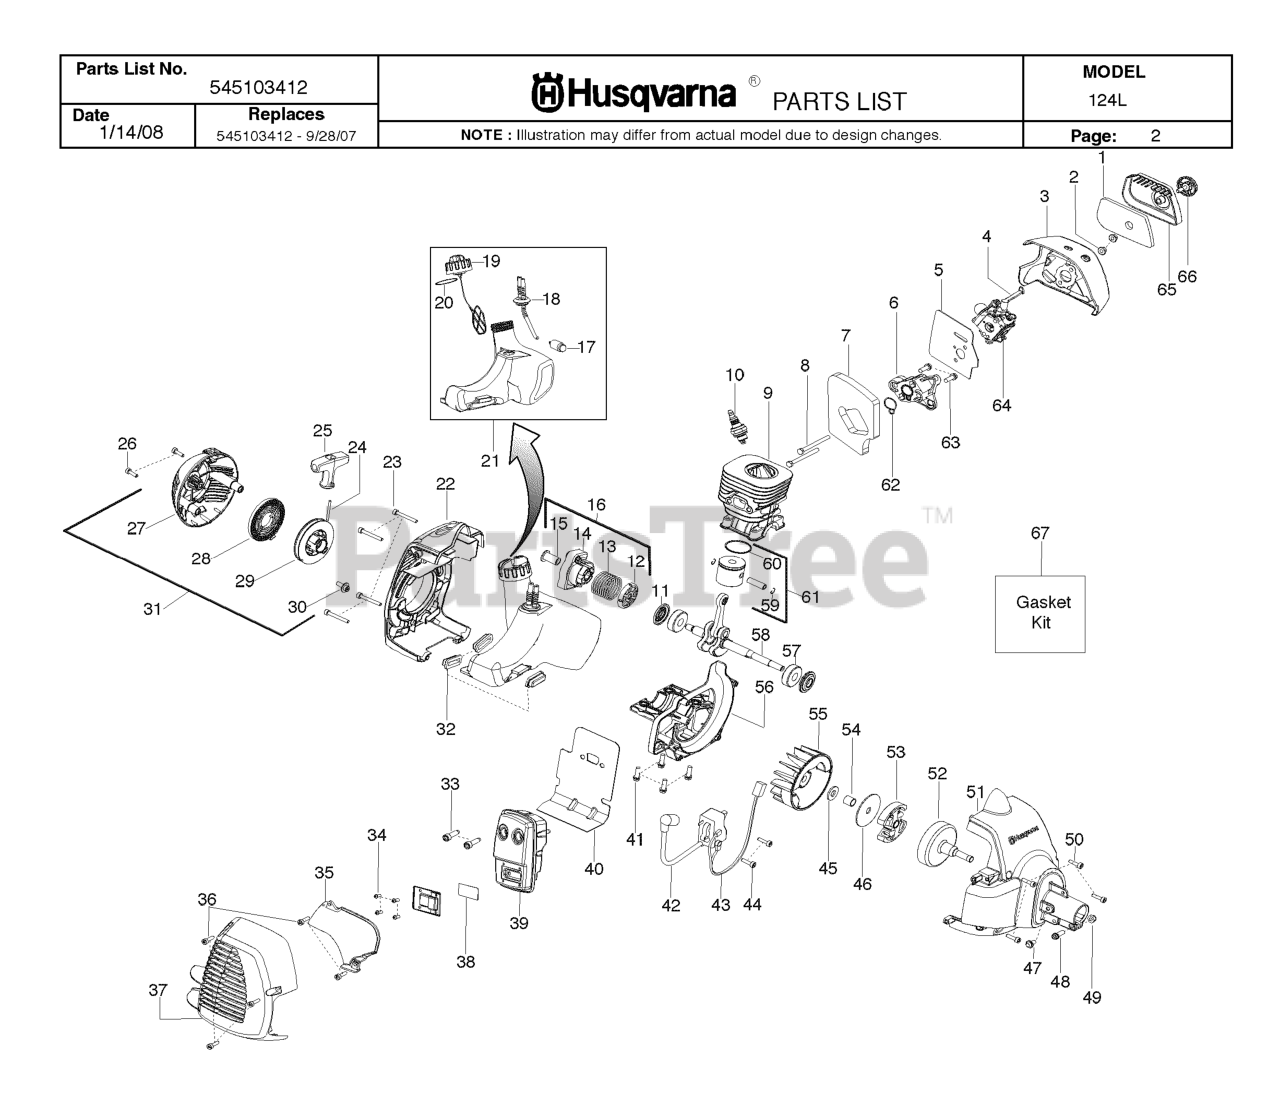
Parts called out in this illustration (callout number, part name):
1	FILTER AIRBOX
4	CHOKE LEVER
5	KIT GASKET CARB
6	CARB ADAPTOR
7	KIT GASKET 28CC TRIMMER
8	BOLT CARB ADAPTOR
9	CYLINDER
10	Accy - Spark Plug (RCJ6-Y)
11	KIT SEAL CRANKSHAFT
16	COUPLING-STARTER
17	FUEL PICK-UP ASSY
18	KIT FUEL LINE
19	ASSY-CAP W/RETAINER
20	O RING NITRILE
21	FUEL TANK ASSY
22	REAR SHROUD
25	STARTER HANDLE GRAY
26	SCREW M5-0.8X30MM
27	STARTER HOUSING
28	%KIT STARTER SPRING
29	KIT STARTER PULLEY
31	ASSY-STARTER HSG.
32	ISOLATOR FUEL TANK
33	BOLT MUFFLER
34	SCREW-10-16 X 1/2 HI-LO
35	SHIELD HEAT
36	SCREW M4 X 1.75 PT 16MM
37	GUARD-MUFFLER
38	KIT SPARK ARRESTOR SCREEN
39	ASSY-MUFFLER
40	GASKET PAPER METAL
41	SCREW-M5-0.8 X 25MM(TAP)
42	IGNITION MODULE MB45
43	ASSY MODULE LEAD WIRE
44	SCREW M4 X .70 TT 16MM
45	WASHER CLUTCH
46	WASHER-CLUTCH
49	LOCKNUT-HEX 10-24
50	SCREW M4 X .70 TT 16MM
51	FAN HSG ASSY
53	%KIT CLUTCH ASSY
54	SPACER FLYWHEEL
56	CRANKCASE CASTING
57	BEARING RADIAL BALL (6201)
58	KIT CRANKSHAFT ASSY
59	WRIST PIN RET.
60	RING PISTON
61	KIT PISTON 28CC TRIMMER
62	KIT GASKET 28CC TRIMMER
63	SCREW-M5-0.8 X 25MM(TAP)
65	COVER-AIR BOX
66	KNOB ASSY AIRBOX COVER
67	KIT GASKET 28CC TRIMMER
